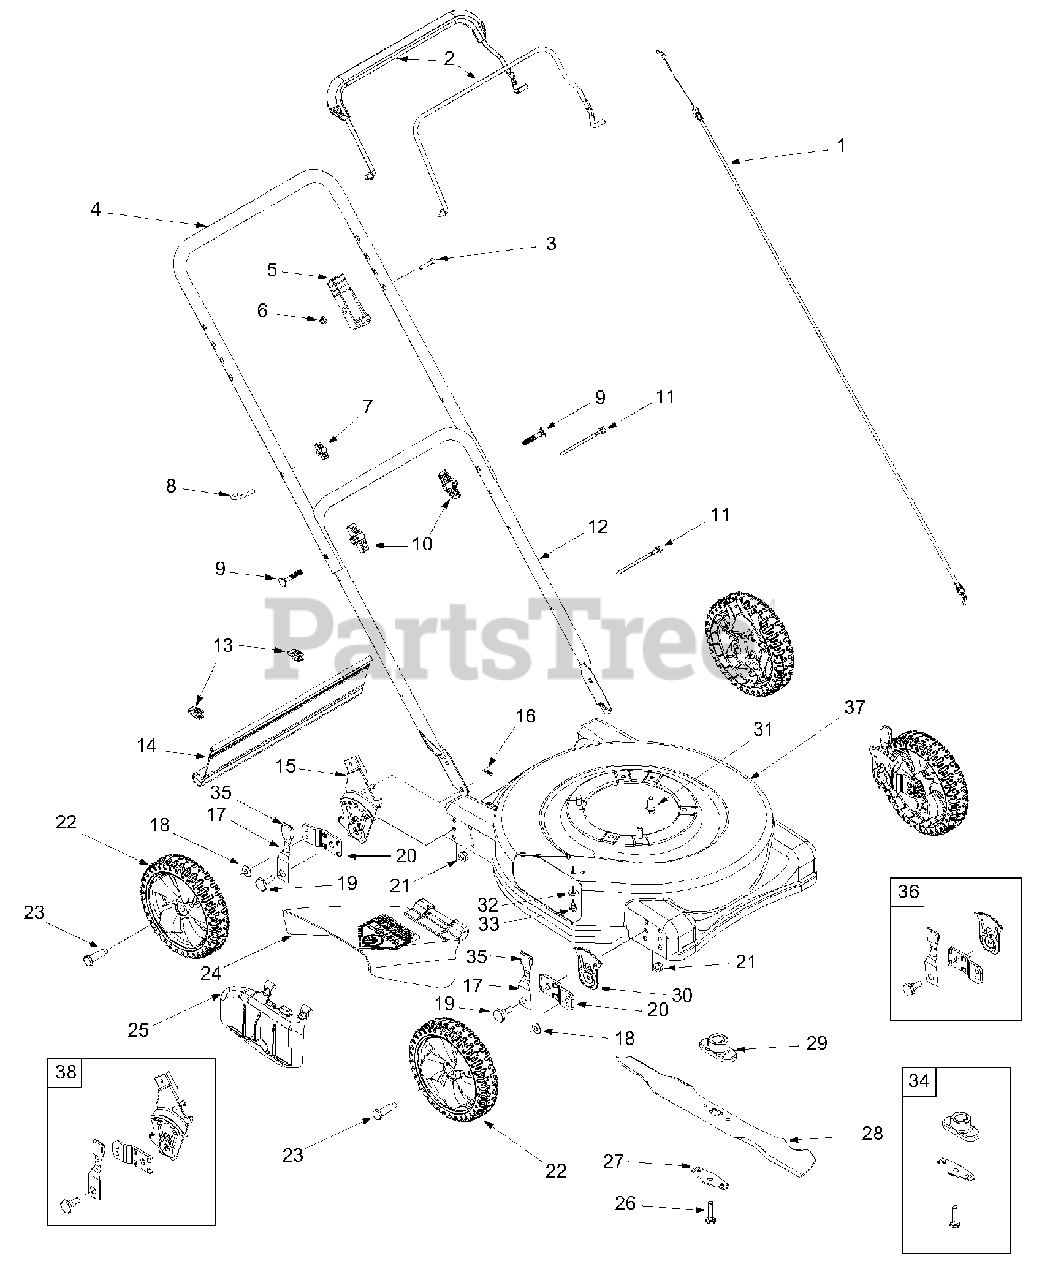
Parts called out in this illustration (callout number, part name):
1	Control Cable - 40.5"
3	Oval C-sunk Machine Screw
5	Control Cable Housing
6	Hex Lock Nut, Nylon, 1/4-20 GR8
7	WIng Knob
8	Eye Bolt
9	Carriage Bolt
10	Wing Knob
11	Cable Tie
13	Hinge Clip
14	Rear Trail Shield
15	Height Adjustment Bracket, RH
16	Internal Cotter Pin
17	Spring Lever
18	Bell Washer, .400 ID x .88"
19	Shoulder Bolt, 1/2 x .357"
21	Flange Lock Nut, 3/8-16
22	Wheel Assembly
23	Shoulder Screw, .498 x 1.445 : 3/8-16
24	Side Discharge Chute
25	Mulch Plug (If Equipped)
26	Hex Head Cap Screw, 3/8-24 x 1.5 GR8
27	Blade Bell Support
28	Standard Blade
29	Blade Adapter w/Star
30	Height Adjustment Plate
31	Self Tapping Screw, 3/8-16 x 1"
32	Bell Washer
33	Self Tapping Screw, 1/4-20 x 1/2"
34	Blade Adapter Kit
35	Height Adjuster Knob
36	Front Height Adjuster Assy, RH
